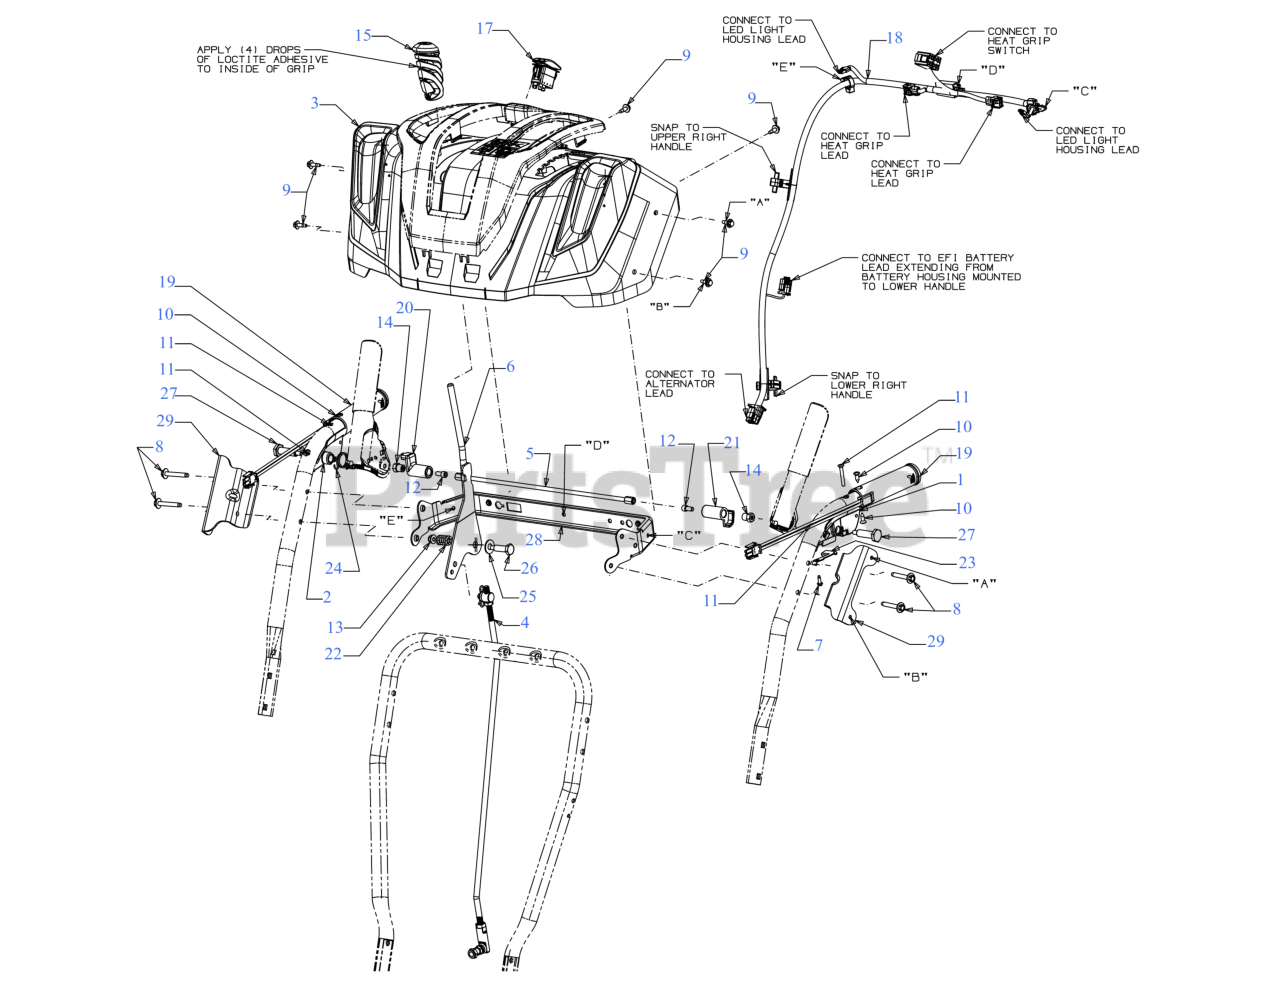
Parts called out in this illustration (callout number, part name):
1	CLUTCH LOCK HANDLE ASSEMBLY (LH)
2	CLUTCH LOCK HANDLE ASSEMBLY (RH)
3	PANEL ASSEMBLY
4	SHIFT ROD ASSEMBLY
6	SPEED SHIFT CONTROL (POWDER BLACK)
7	SCREW #8-16 x .50
8	SCREW 1/4-20 x 1.625
9	SCREW M6-1 x .625
10	SCREW-AB #12-24 x .625
11	SCREW #10-24 x 1.375
12	SCREW 1/4-20 x .50
13	FLANGE LOCK NUT
14	HEX NUT W/PATCH
15	PTO HANDLE GRIP .355 ID
17	HEATED GRIP SWITCH
18	HEADLIGHT HARNESS
19	HEATED GRIP
21	CLUTCH LOCK CAM
22	COMPRESSION SPRING
23	CLUTCH SPRING
24	TORSION SPRING
25	FLAT WASHER .40X.88X.060
26	SHOULDER SCREW
27	SHOULDER SCREW .437 x 1.345 1/4-20
28	HANDLE SUPPORT BRACKET (POWDER BLACK)
29	HANDLE PANEL BRACKET (POWDER BLACK)
